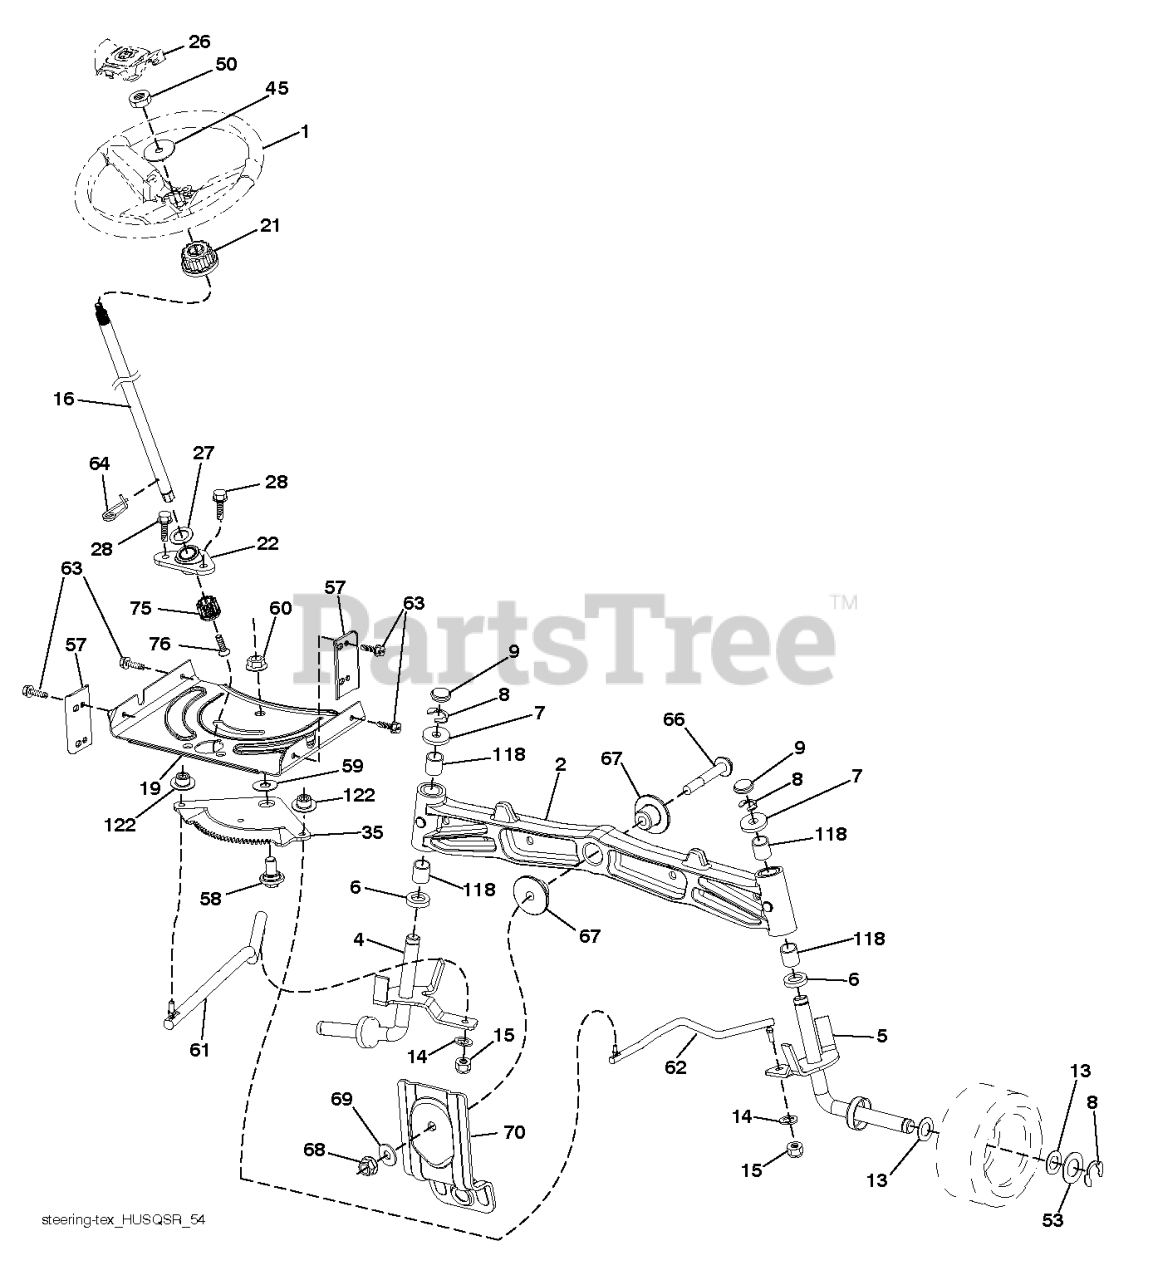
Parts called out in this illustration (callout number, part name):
1	WHEEL.STEER.HUSQ.SR.498.OVMLD
2	AXLE.SVC.ASM CAST IRON.TEX
4	SPINDLE.WELDED.LH.15"TEX
5	SPINDLE.WELDED.RH.15"T
6	THRUST WASHER
9	CAP.SPINDLE.BLACK
14	SLW 3/8 STD
15	NUT CROWNLOCK 3/8-24
16	SHAFT.STEER.2HIGH.SPLND.PLATED
19	PLATE.STEER.DDL.NLT/NG
21	ADAPTER.WHEEL.STEER.SPLND.ALUM
22	BEARING.SHAFT.STEER.LOWER.625
26	INSERT.CAP.WHL.STRG.HUSQ.PREM
27	WASHER LT
28	SCREW, 3/8-16X3/4
35	GEAR.SECTOR.PLATE.DDL.
45	WASHER.3/8ID.2-3/8OD.12GA.PLTD
50	NUT LOCK FLG 3/8-16 UNC
53	WASHER.HARDENED
57	BRACKET.UPSTOP.TEX
58	BOLT.SHOULDER.SECTOR.P
59	WASHER.THURST.SECTOR.S
60	NUT FLANGE LOCK 5/8-11
61	LINK.ASM.DRAG.ADJUST.LH.PLATED
62	LINK.ASM.DRAG.ADJUST.RH.PLATED
63	SCREW
64	RETAINER.CLIP.SPRING.S
66	BOLT HEX FGHD 7/16-14 X 3 SERR
67	BUSHING.PM.FRONT AXLE
68	NUT.LOCK.FLANGE.7/16
69	WASHER.1.5X.505X.118
70	BRACKET.FRT.DECK.SUSP.RR.MT431
75	PINION.ZINC PLATED
76	SCREW HEAD SOCKET LRVB
118	BUSHING, AXLE CAST
122	CAP.GEAR.SECTOR.TEX
